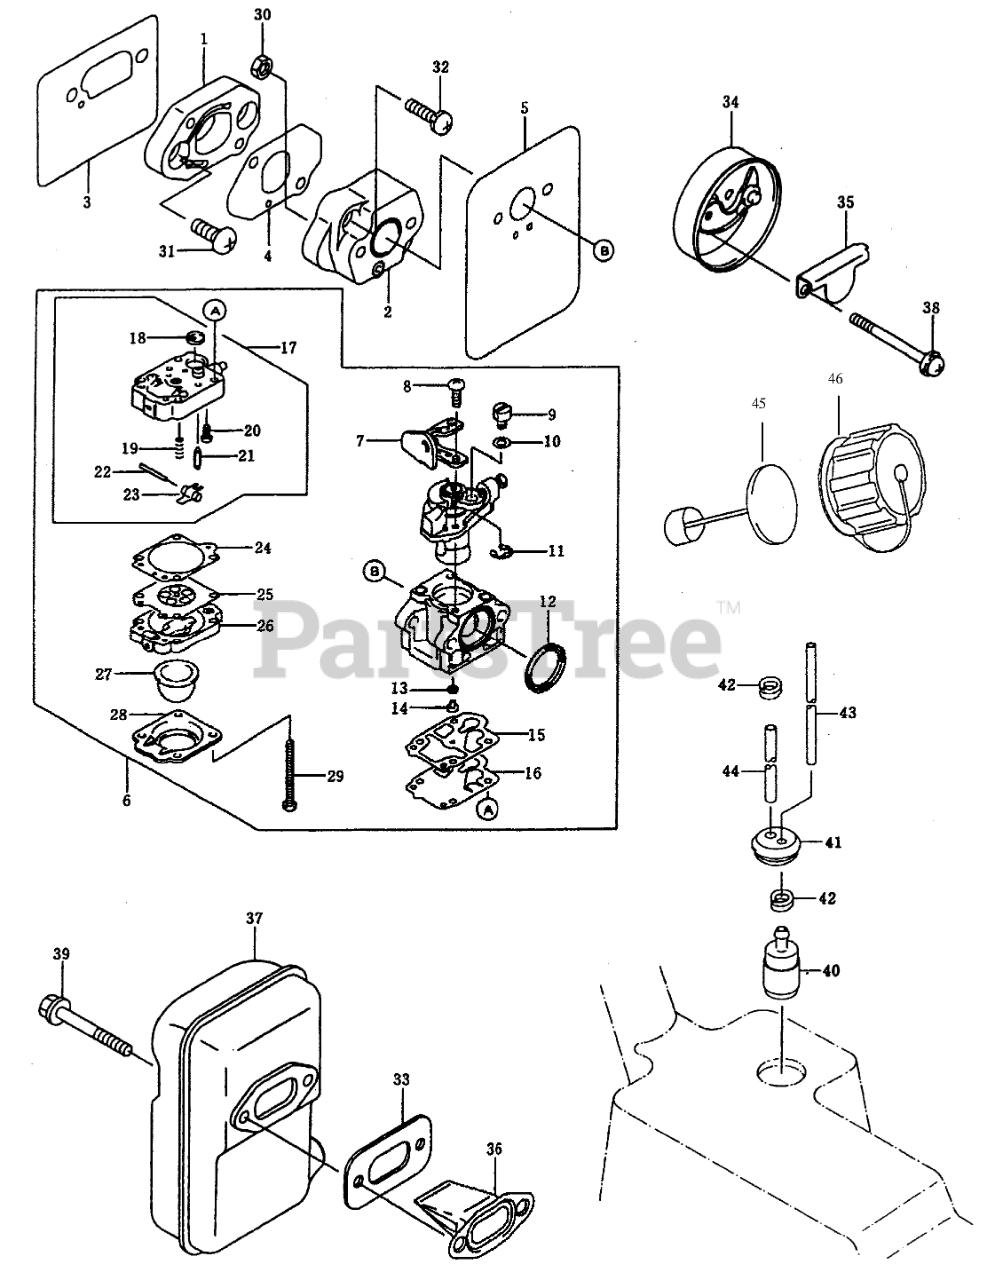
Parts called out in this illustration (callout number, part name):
1	ADAPTER
2	INSULATOR
3	GASKET "A"
4	GASKET "B"
5	GASKET "C'
6	Carburetor Assembly (Inc. Ref. # 7-29)
7	Bracket
9	Arm
10	Washer
11	Snap Ring
12	Packing
14	Main Jet
15	Gasket
16	Diaphragm
17	Body Assembly (Incl. Ref. # 18-23)
18	Filter
21	Float Valve
23	Lever
24	Gasket
25	Diaphragm
27	PUMP-PRIMING
28	Cover-Primer Pump
30	NUT,M5
31	SCREW,PAN
32	SCREW,PAN-WP
33	GASKET,MUFFLER
34	CASE,ASSY-AIR FILTER
35	BAFFLE
36	ARRESTER-SPARK
37	MUFFLER-COMP
38	SCREW
39	BOLT,6 X 65
40	FILTER-FUEL
41	GROMMET,FUEL TANK
42	CLAMP,FUEL FILTER
43	TUBE,3 X 5 X 250
44	TUBE,3 X 6 X 130
45	BREATHER
46	CAP-ASSY-TANK
